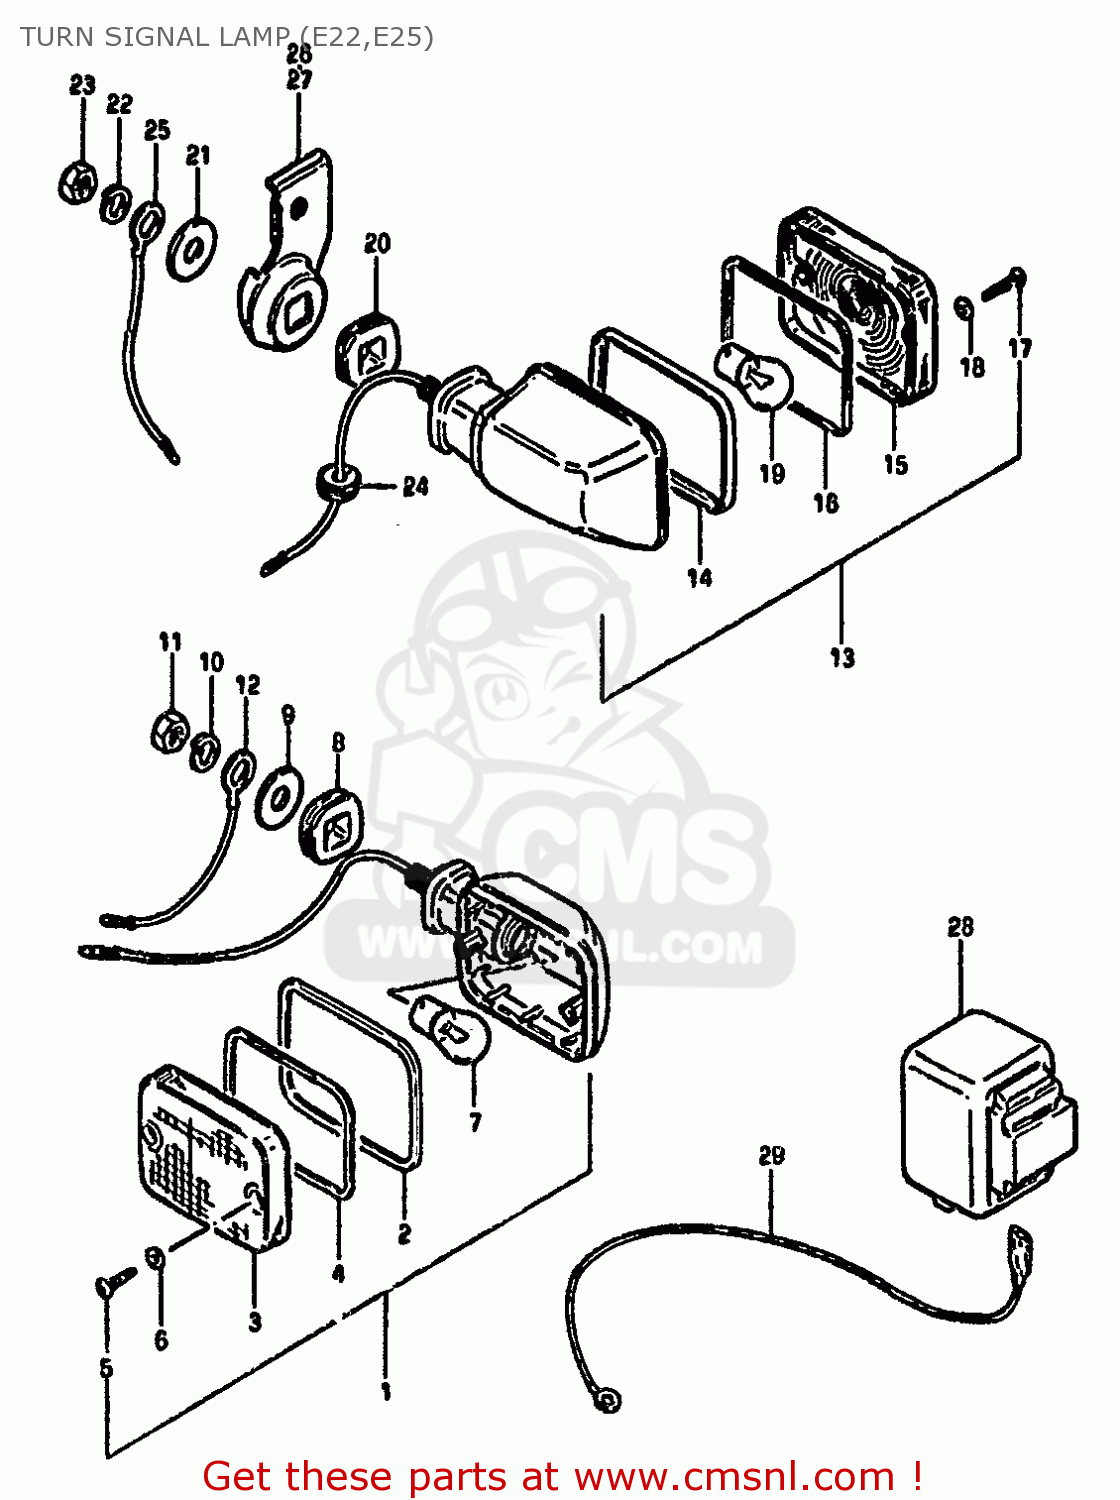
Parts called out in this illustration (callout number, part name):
1	LAMP ASSY,FR T
2	RIM
3	LENS
4	GASKET (NAS)
5	SCREW
6	GASKET (NAS)
7	BULB(12V21W)
8	CUSHION
9	WASHER (10.5X30X2.3)
10	LOCK WASHER
11	NUT
12	WIRE
13	LAMP ASSY,RR T
14	RIM
15	LENS
16	GASKET (NAS)
17	SCREW
18	GASKET (NAS)
19	BULB(12V21W)
20	CUSHION
21	WASHER (10.5X30X2.3)
22	LOCK WASHER
23	NUT
24	GROMMET
25	WIRE
26	BRACKET,REAR TURN SIGNAL
27	BRACKET,REAR TURN SIGNAL
28	RELAY, TURN SIGNAL
29	LEAD WIRE, RELAY EARTH
